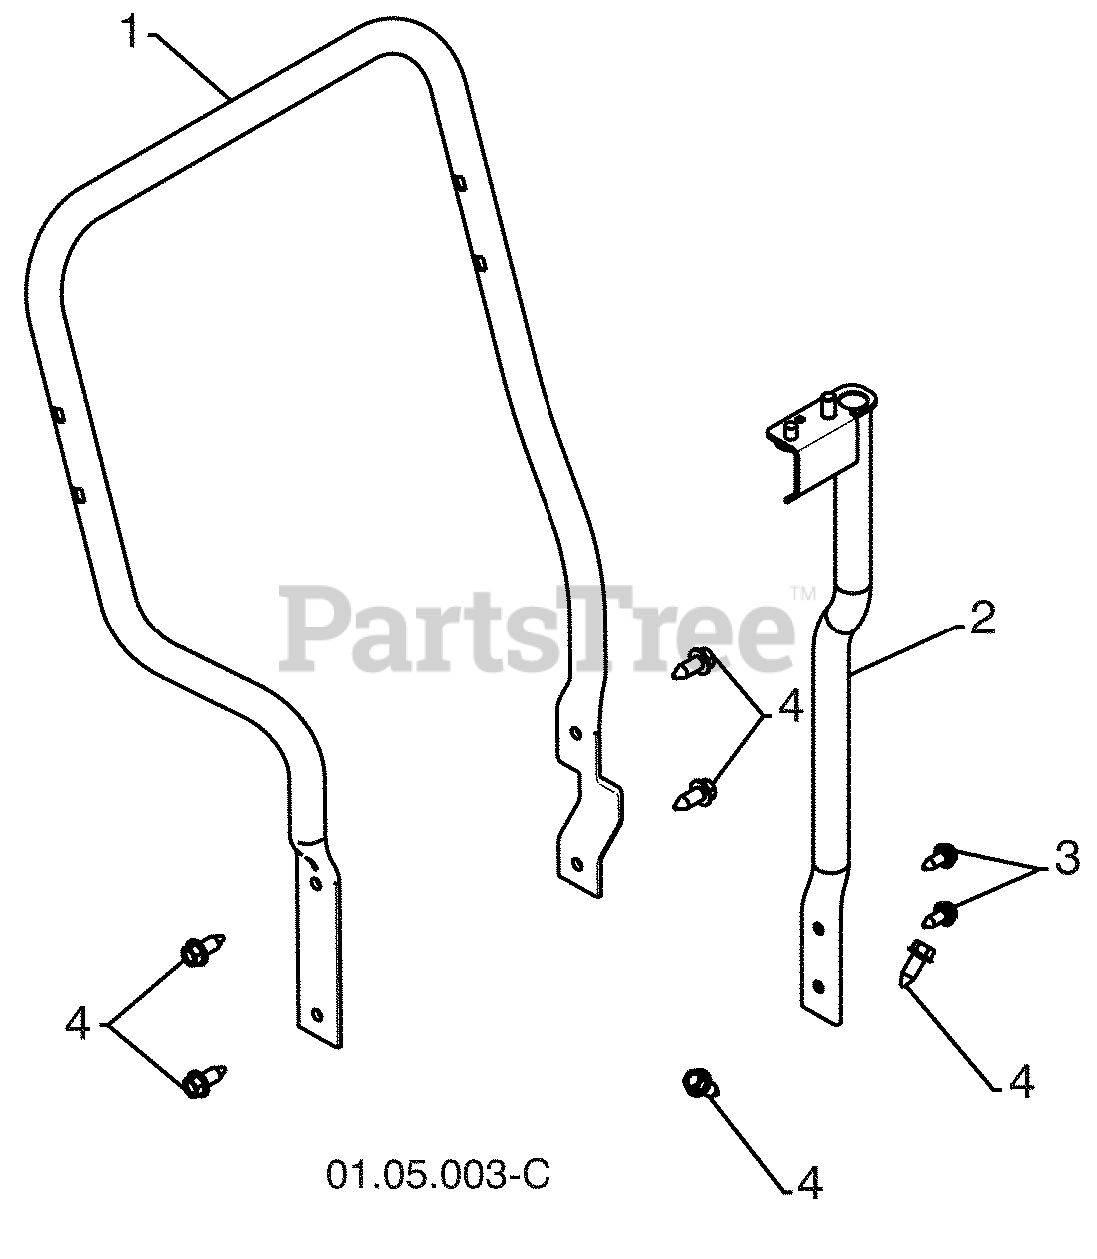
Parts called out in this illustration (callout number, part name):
1	TUBE.LOWER.HANDLE.SNOW.GRAY
2	SUPPORT.WELDMENT.ROTATOR.
3	BOLT.HEX.HD.WASHER.5/16-18X.75
4	SCREW 3/8-16X1
